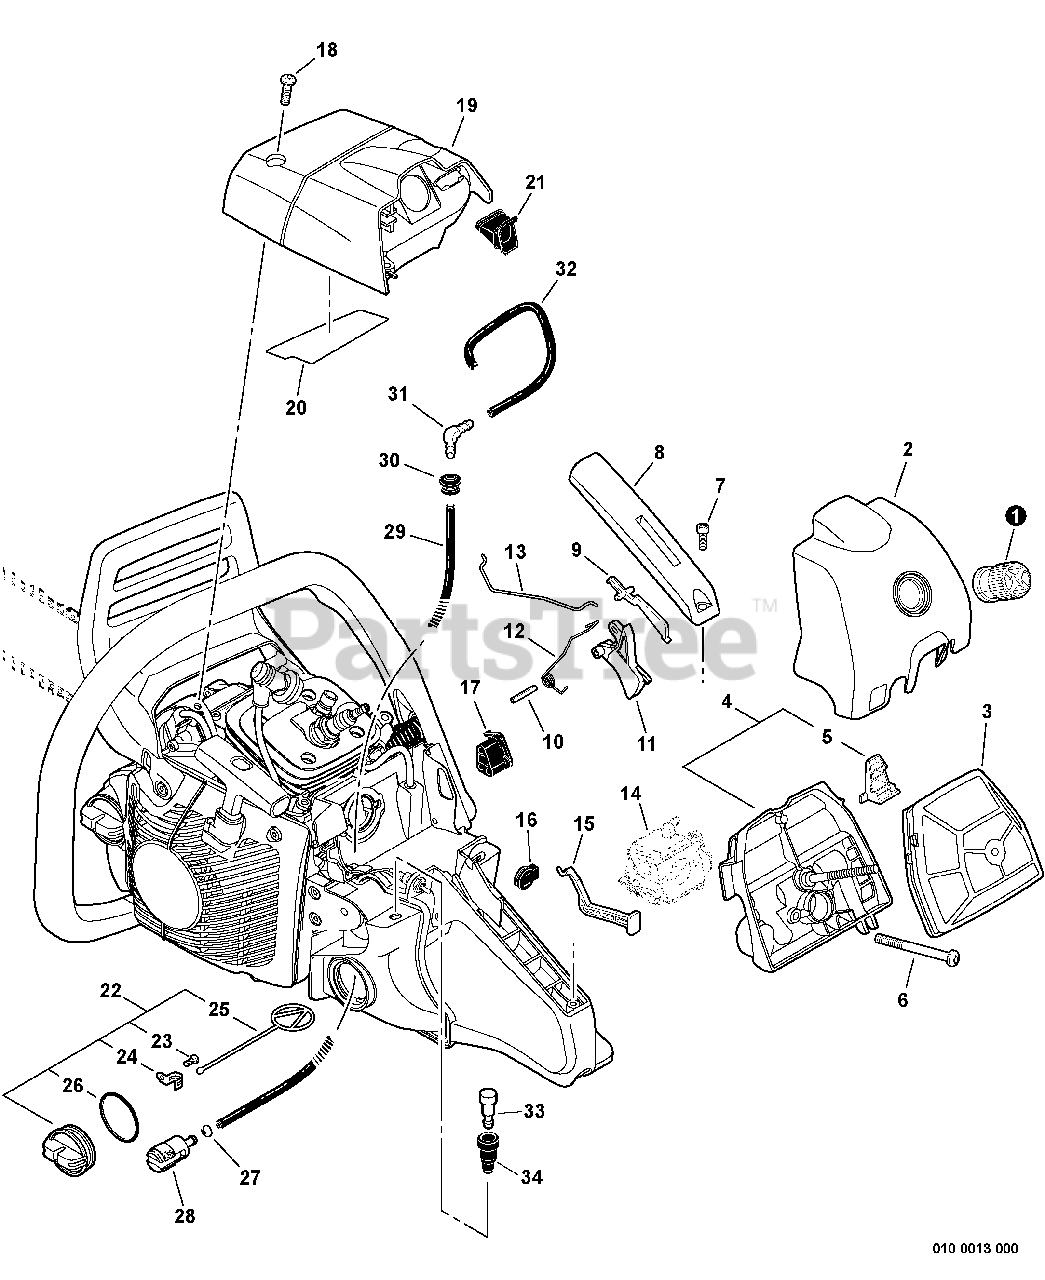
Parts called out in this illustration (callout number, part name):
1	THUMBSCREW
2	COVER, AIR FILTER
3	FILTER, AIR
4	AIR FILTER CASE KIT
5	SHUTTER, AIR
6	SCREW - 5X50
7	SCREW - 4X12
8	COVER, HANDLE
9	LEVER, TRIGGER LOCKOUT
10	PIN - SPRING -- 4X25
11	TRIGGER, THROTTLE
12	SPRING, TRIGGER
13	ROD, THROTTLE
14	CARBURETOR
15	ROD, CHOKE
16	GROMMET
17	GROMMET
18	SCREW - 5X16
19	COVER, ENGINE
20	DEFLECTOR, HEAT
21	DUCT, AIR
22	CAP ASSY
23	SCREW - 3X8
24	RETAINER
25	CONNECTOR, CAP
26	O-RING - 29
27	CLIP - 6
28	FILTER, FUEL
29	PIPE - 3X5X120 -- BLACK
30	GROMMET
31	CONNECTOR, PIPE
32	PIPE - 3X6X135 -- BLACK
33	VENT, FUEL TANK
34	HOLDER, VENT
